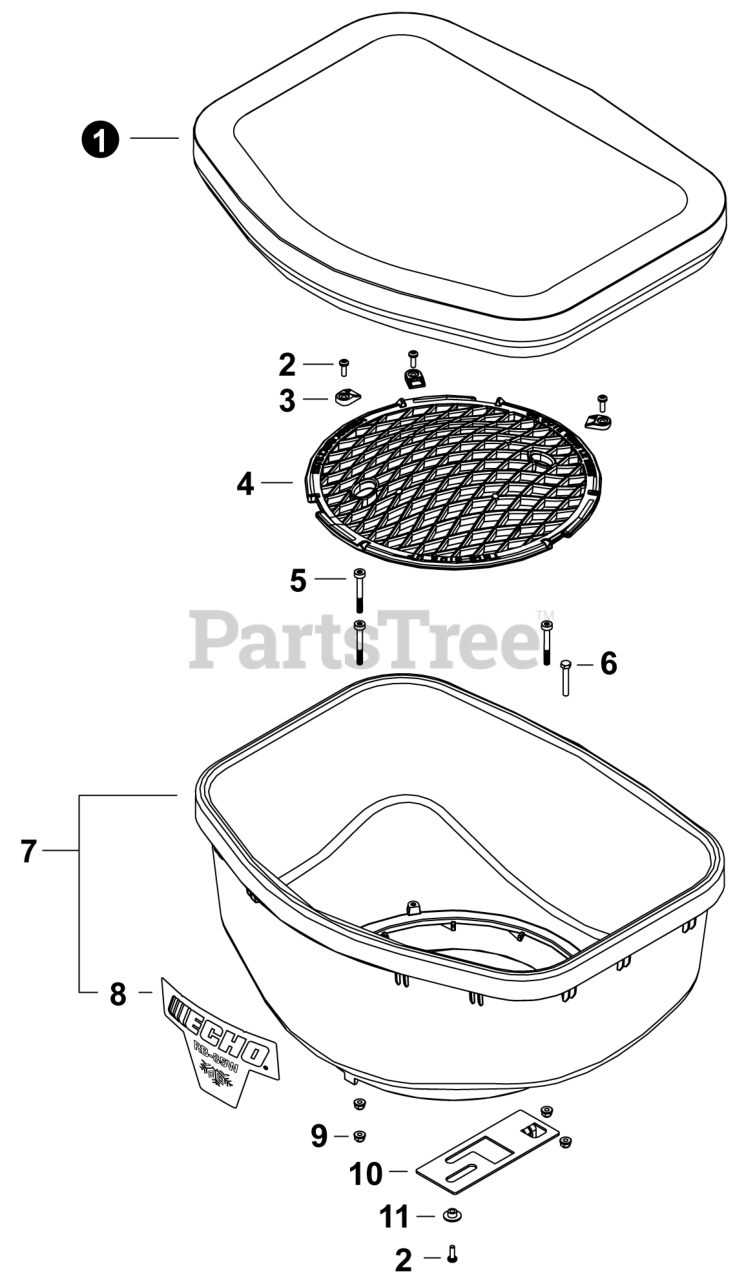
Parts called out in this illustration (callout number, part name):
1	COVER, HOPPER
2	SCREW, TAPPING 5x16
3	CLIPS, SCREEN
4	SCREEN, HOPPER
5	BOLT, M6 X 50MM
6	BOLT 6x40
7	HOPPER ASSY
8	LABEL - RB-85W
10	PLATE, REGULATOR
11	BUSHING - SLEEVE
